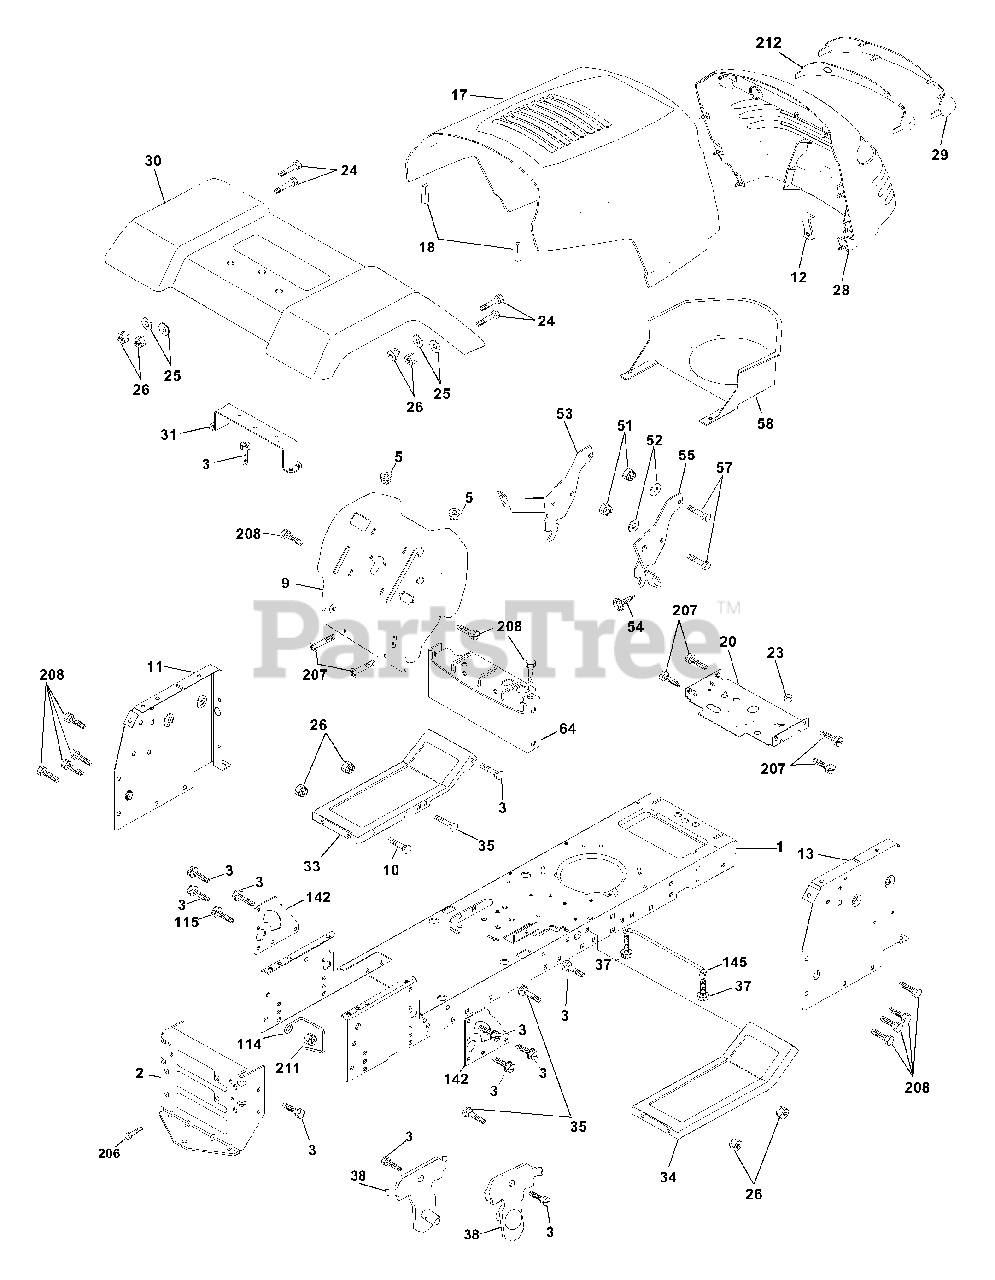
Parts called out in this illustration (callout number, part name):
1	Chassis
2	Drawbar
3	Screw 3/8-16x.75
5	Bumper Hood/Dash
9	Dash P/L
10	Bolt Carriage 3/8-16 x 1
11	Panel Dash Lh
12	Clip Tinnerman
13	Panel Dash Rh
17	Hood LT/PL
18	Bumper Hood
20	Plate Mtg Battery Fuel Tank Fr
23	Bushing
24	Bolt Fin Hex 3/8-16 x 1 Gr 5
25	Washer 13/32 X 13/16 X 12 Ga
26	Nut Lock Hex W/Ins 3/8-16 Unc
28	Grille LT/PL
29	Lens LT/PL
30	Fender Footrest STLT Pnt
31	Bracket Support Fender
33	Footrest Pnt Lh
34	Footrest Pnt Rh
35	Bolt Rdhd Sht Sqnk 3/8-16 x 3/4
37	Screw Thdrol 6/16-18 x 1/2 TYT
38	Bracket Asm. Pivot Mower Rear
51	Nut Lock Hex W/Ins 1/4-20
52	Washer 9/32 x 7/8 x 16 Ga.
53	Bracjet Grukke Lh
54	Screw Hex Wshd 8-18 x 7/8
55	Bracket Grille Rh
57	Bolt Hex 1/4-20 x 3/4
58	Duct Air
64	Dash Lower STLT
114	Keeper Belt Rear Lh
115	Screw 3/8-16 x 1-1/4
142	Plate Reinforcement STLT
145	Rod Pivot Chassis/Hood
206	Bolt Shoulder 5/16-18
207	Screw Thdrol 5/16-18 x 1/2
208	Screw Thdrol 3/8-16 x 1/2
211	Nut Hexflange Lock
212	Insert Lens Reflect P/L LT
